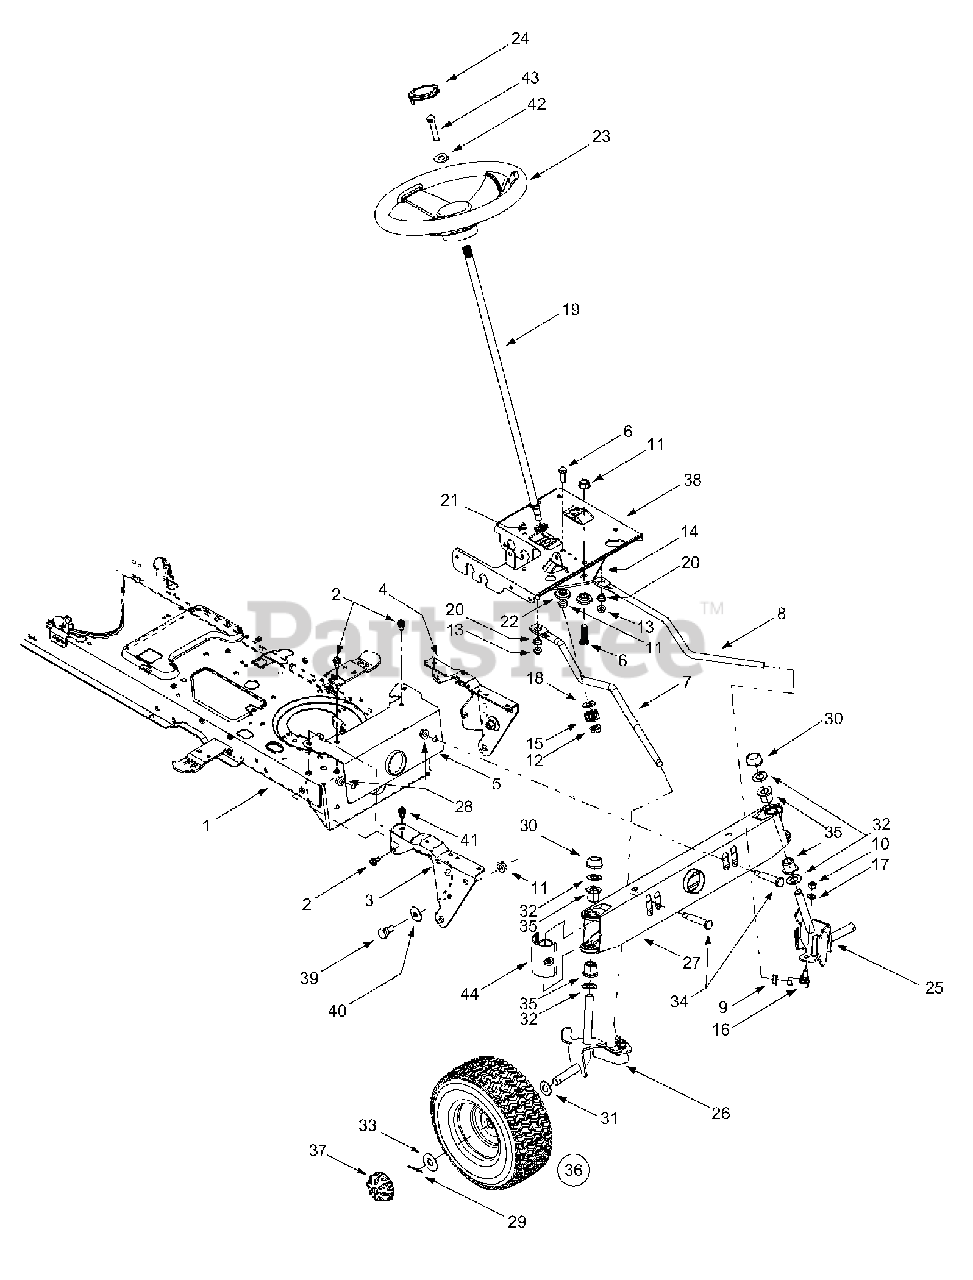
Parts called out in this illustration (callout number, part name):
6	Hex Cap Screw, 3/8-16 x 1.25 (Grade 5)
7	RH Drag Link
8	LH Drag Link
9	Jam Nut, 7/16-20 (Grade 2)
10	Hex Nut, 3/8-24 (Grade 2)
11	Flange Lock Nut, 3/8-16
12	Flange Lock Nut, 7/16-20
13	Flange Lock Nut, 5/16-18
14	Steering Gear, 11/90 Ratio
15	Steering Pinion Gear
16	Ball Joint, 7/16-20
17	Lock Washer, 3/8
18	Flat Washer, .51 x 1.12 x .06
19	Steering Shaft, .625 OD x 24.4
20	Plastic Bushing, .38 ID
21	Hex Flange Bearing, 5/8
22	Shoulder Spacer, .38 ID
23	Steering Wheel, Soft Grip, Three Spoke
24	Steering Wheel Cap, Round
25	LH Axle Assembly, .625 Diameter
26	RH Axle Assembly, .625 Diameter
28	Flange Lock Nut, 3/8-16
29	Cotter Pin
30	Push Cap, .625
31	Flat Washer, .64 x 1.0 x .12
32	Flat Washer, .64 x 1.24 x .06
33	Flat Washer, .635 x 1.589 x .06
34	Shoulder Screw, .5 x 2.2, 3/8-16
35	Flange Bearing, .632 ID x .937 OD
37	Deluxe Hub Cap
39	Shoulder Screw, 3/8-16
40	Bell Washer, .39 x 1.13 x .062
41	Self-tapping Screw, 5/16-18 x .75
42	Bell Washer, .34 x .872
43	Hex Bolt, 5/16-18 X 1
44	Pivot Bar End Cap w/ Fitting
